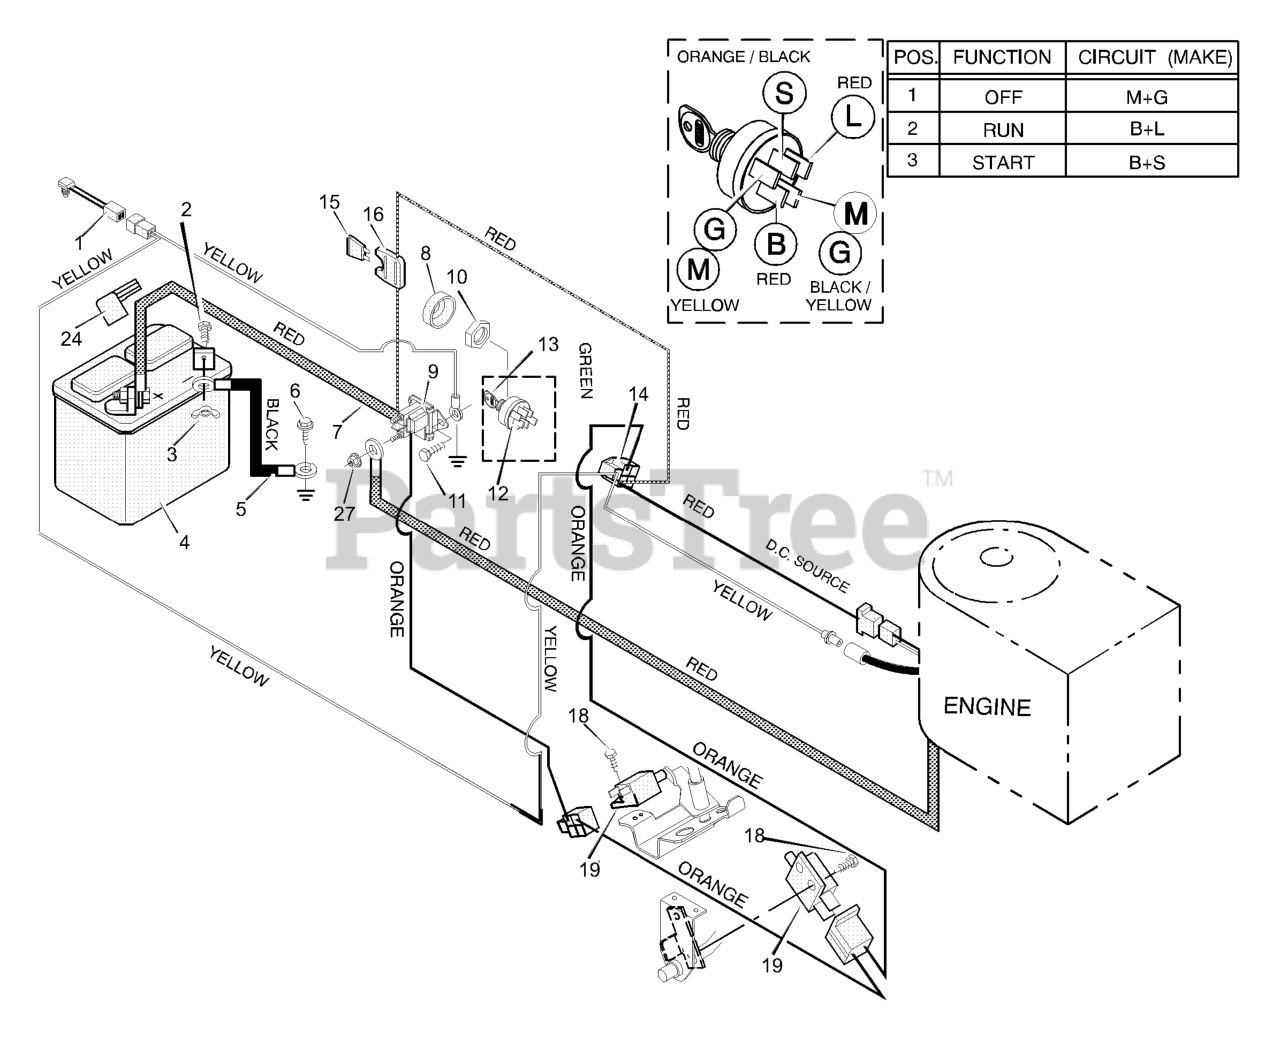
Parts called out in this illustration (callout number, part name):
1	Switch, Seat Sensor
2	Bolt
3	Wingnut
4	Battery
5	Cable, Battery Ground
7	Cable, Red Battery
8	Cap, Ignition
9	Solenoid
10	Nut
12	Switch, Ignition
13	Key, Ignition
14	Harness, Chassis Wire
16	Holder, Fuse
17	Switch, Clutch
19	Switch, Clutch
24	Cover, Terminal
27	Locknut
